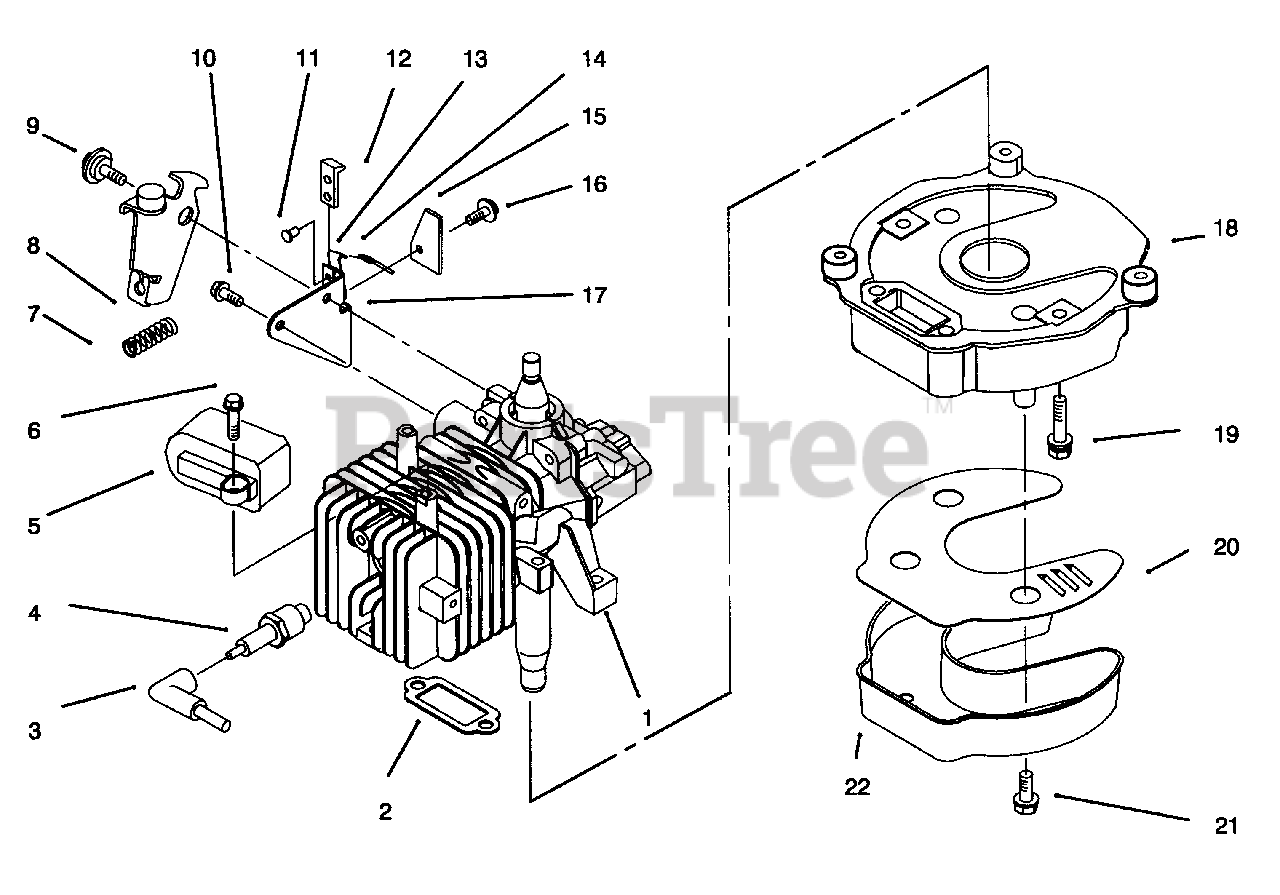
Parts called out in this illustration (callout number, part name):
1	Short Block
2	Gasket-Exhaust
3	Wire-Plug (Includes)
4	Plug-Spark
5	CD Ignition (Incl. Ref. #3)
6	Screw-Hex. Washer Hd.
7	Spring-Compression
8	Brake Plate Assembly
9	Screw-Shoulder
10	Screw
11	Rivet-Plastic
12	Strap-Insulation
13	Strap-Ground
14	Wire-Brake Switch Lead
15	Stop-Ground Strap
16	Screw-Thread Forming
17	Mounting Plate Assembly
18	Plate-Muffler
20	Baffle
22	Cover-Muffler
